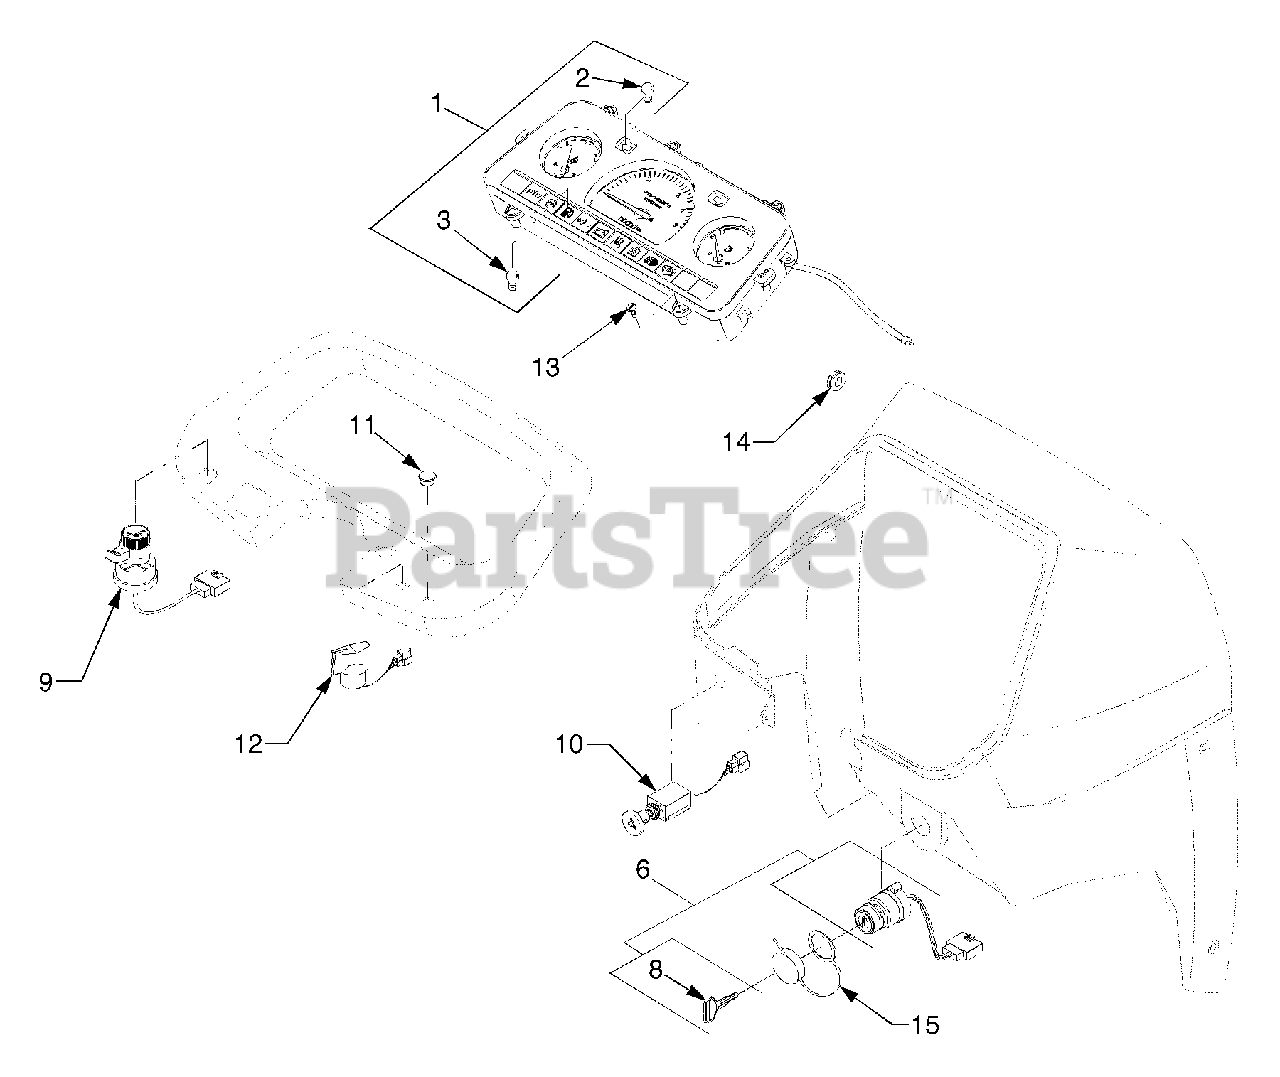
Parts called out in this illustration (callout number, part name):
1	Instrument Meter Ass'y
3	Bulb
6	Starter Switch
8	Key
9	Combination Switch Ass'y
10	Hazard Switch Ass'y
12	Switch, PTO
15	Cover, Starter Switch
